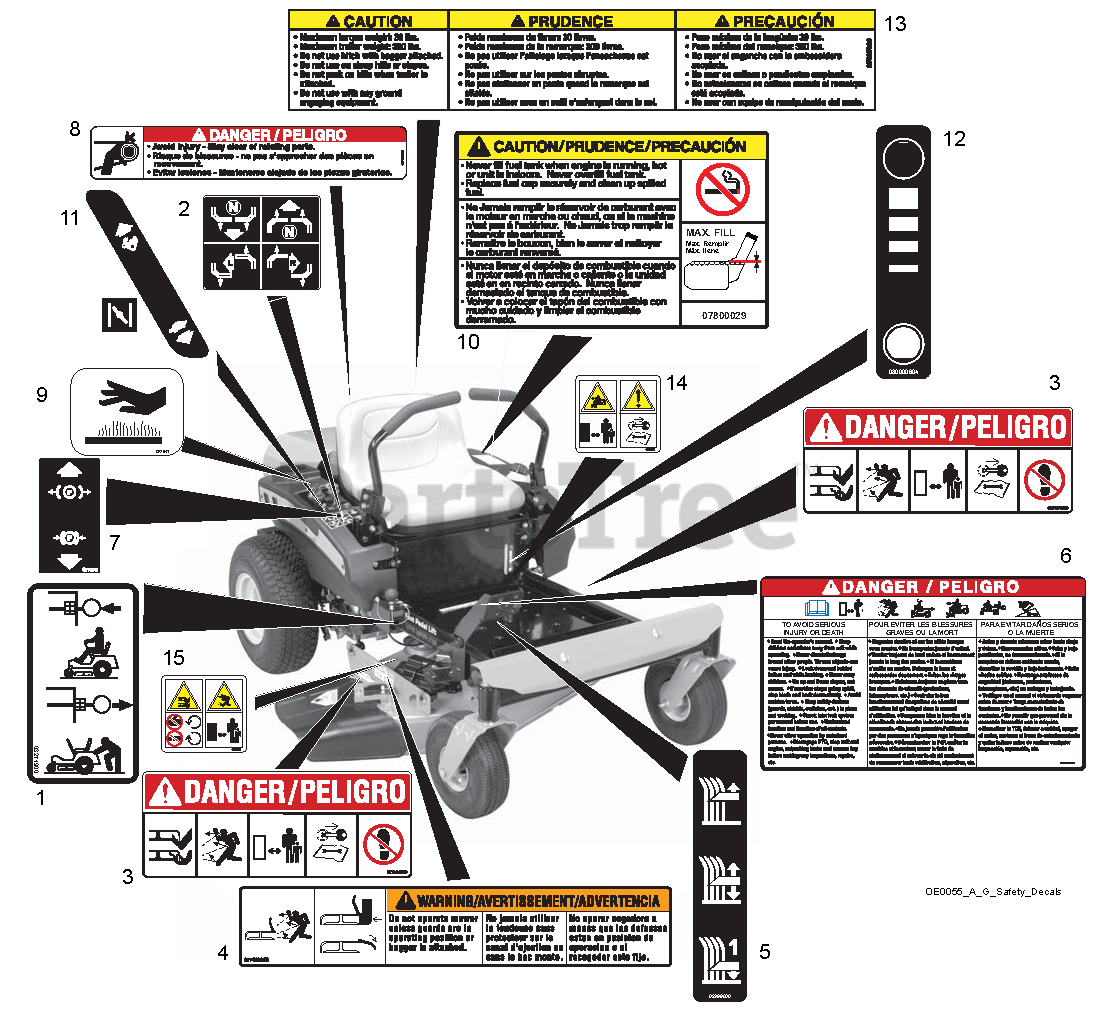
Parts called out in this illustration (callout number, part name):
1	DECAL, TRANSMISSION DISCONNECT
2	DECAL, INSTRUCTIONAL-STEERING
3	DECAL, MOWER PAN DANGER
4	DECAL, WARNING
5	DECAL, CUT HEIGHT
6	DECAL, DANGER BILINGUAL
7	DECAL, PARKING BRAKE LEVER
8	DECAL- DANGER
9	DECAL, HOT SURFACE
10	DECAL-FUEL, WARNING
11	DECAL, SPEED CONTROL
12	DECAL, FUEL LEVEL
13	DECAL, TRAILER HITCH
14	DECAL, CE CAUTION
15	DECAL, CE DECK
